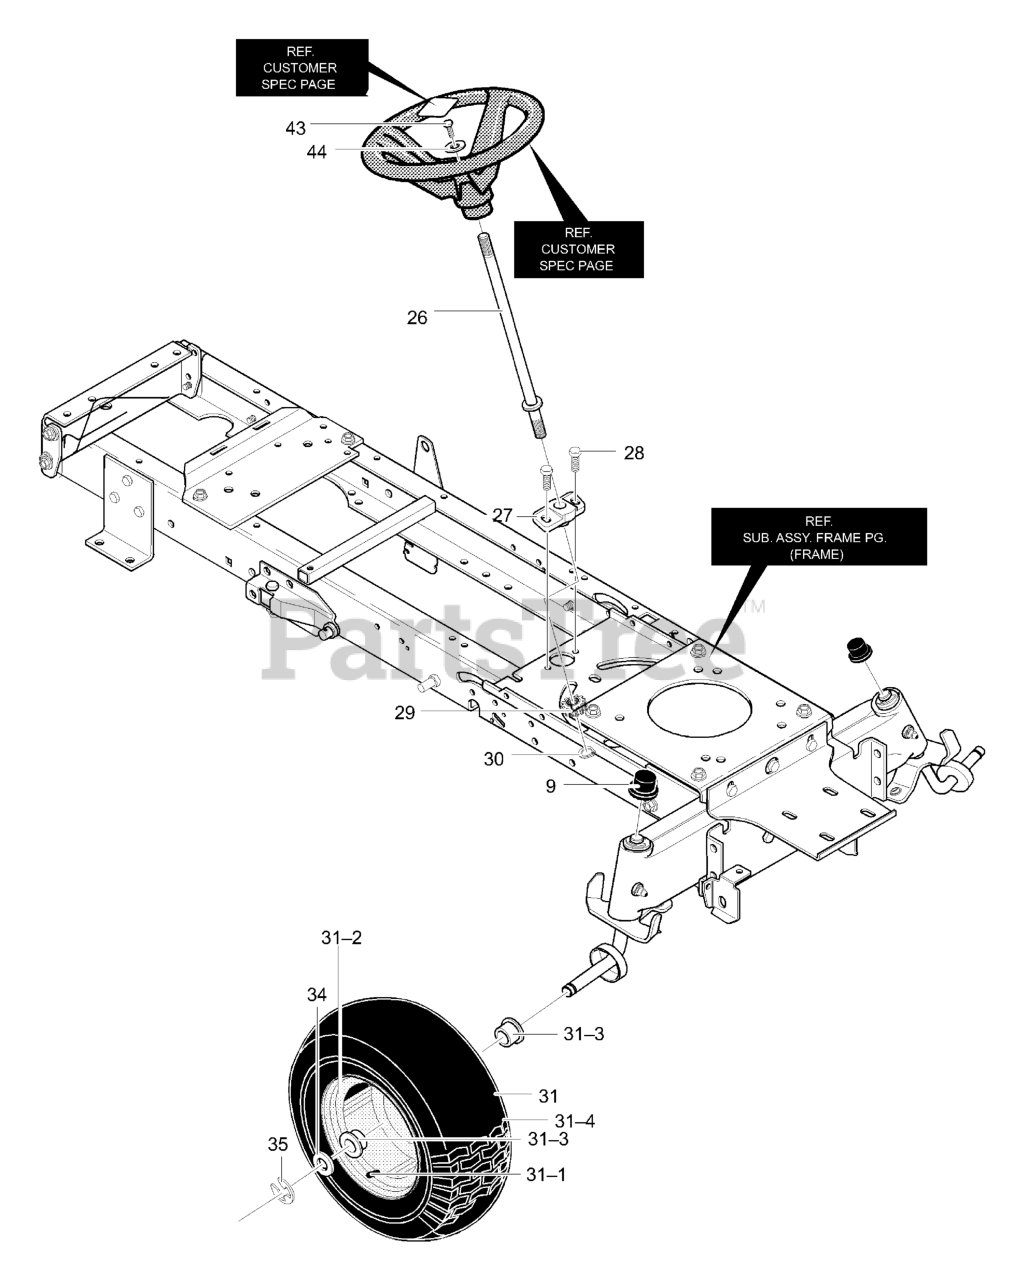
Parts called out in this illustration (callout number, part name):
9	Dust Hb Cap
26	Shaft, Steering
27	Bearing-Lower
28	Screw, 5/16-18 x 0.75
29	Gear, Pinion
30	Retaining Ring
31	Tire & Rim
31-1	Valve Stem
31-3	Bearing
34	Flatwasher
35	E-Ring
43	Screw, 1/4-20x.75
44	Flatwasher
